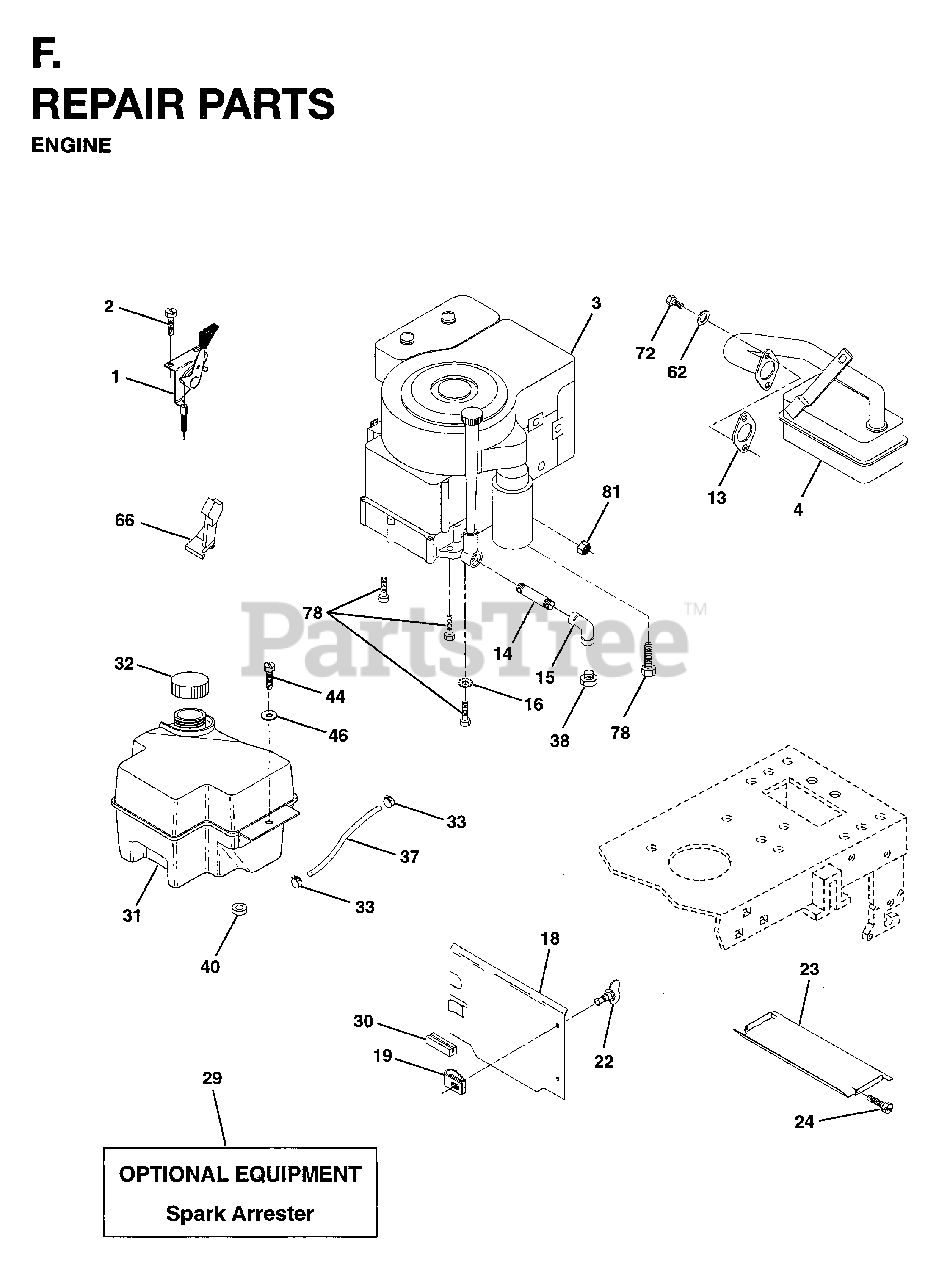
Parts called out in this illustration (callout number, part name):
1	CONTROL
2	BOLT
13	GASKET ENG
15	ELBOW
16	WASHER, LOCK 3/8
18	HEAT SHIELD
19	RECEPTACLE LT
22	STUD 1/4 TURN
23	HEAT SHIELD
29	ARRESTER SPARK (OPTIONAL)
31	FUEL TANK
32	FUEL CAP
33	HOSE CLAMP
37	LINE.FUEL.20
62	LOCKWASHER
66	STOP THROTTLE
72	SCREW
78	BOLT
82	NUT
